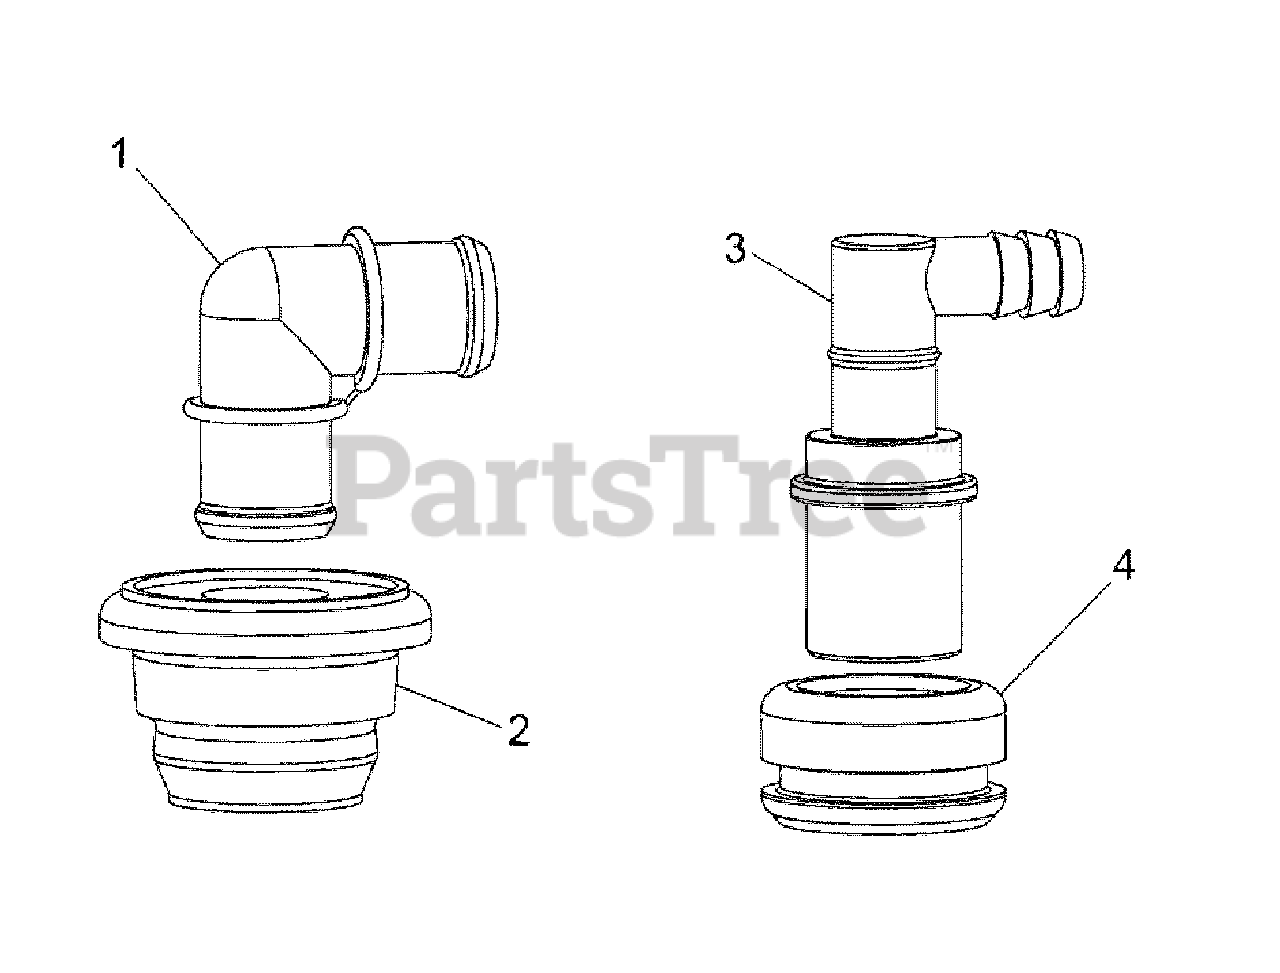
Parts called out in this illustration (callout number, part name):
1	VENT, Elbow
2	GROMMET
4	GROMMET
